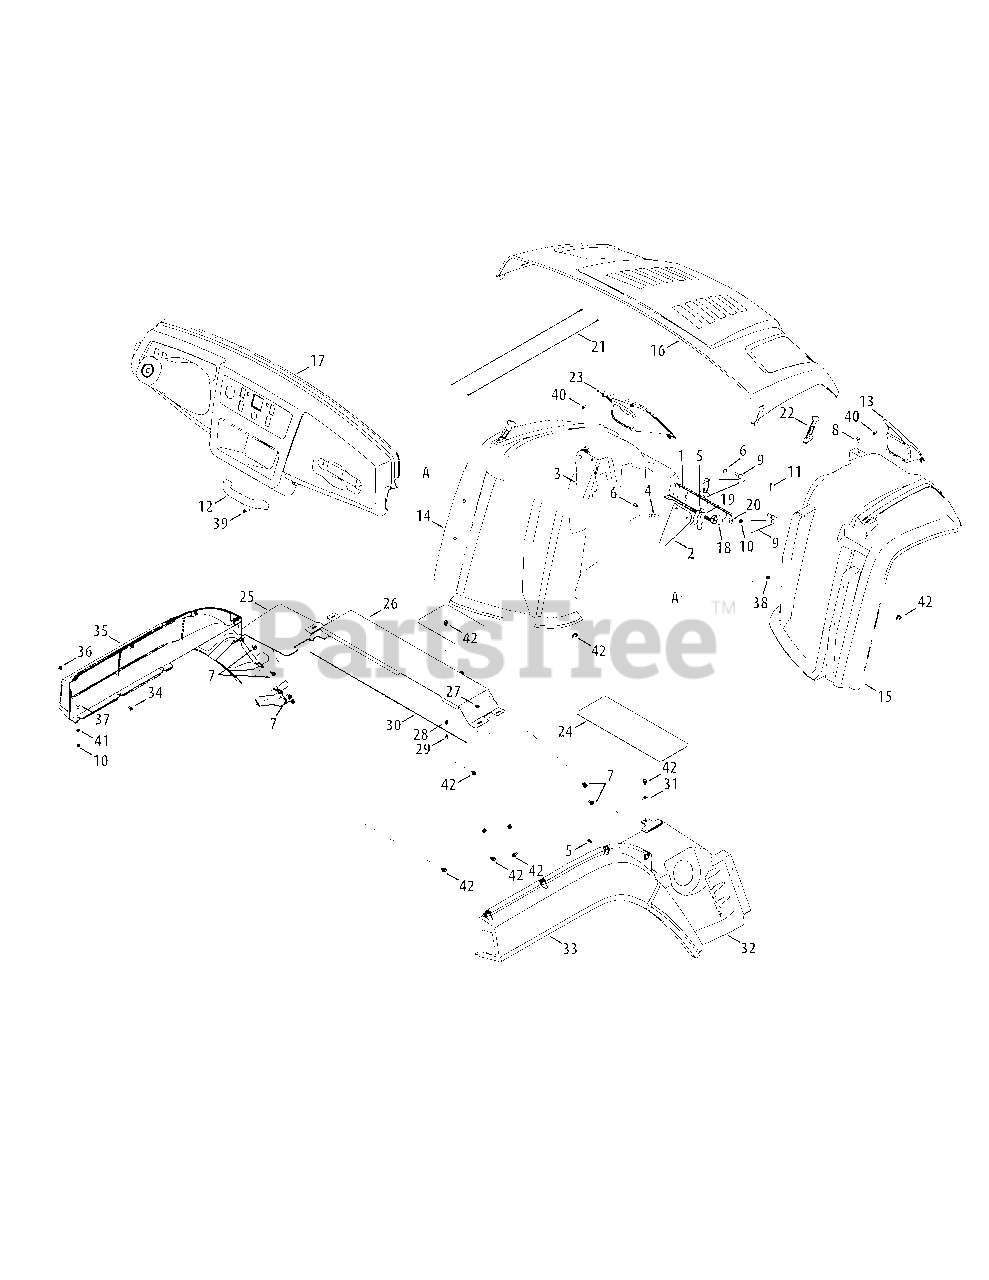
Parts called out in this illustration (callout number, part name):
1	Channel, Frame, Cross
2	Bracket, Hood/dash, Mount, Rh
3	Bracket, Hood/dash, Mount, Lh
4	Screw, 1/4-20, 1.75, Gr5, Std
5	Screw, #12-16 x .50
6	Screw, TT, 1/4-20 x .500
7	Screw, TT, 1/4-15 x .500
8	Hex Head Screw, 1/4-20 x 1.00
9	Rod Assembly, Hood Mount
10	Nut, Flange Lock, 1/4-20
11	Cotter Pin, Internal .08 x 1.42
12	Handle, W/Screw 400/500 S
13	Head Light RH
14	Fender, Lh 4x4
15	Fender, Rh 4x4
16	Hood, 4x4, Green
17	Dash, Uv 4x4
18	Roller, Latch, Hood
19	Spring, Latch, Hood
20	Washer, Flat, .283 x .75 x .030
21	Cable, Hood
22	Strap, Hood
23	Head Light LH
24	Pad, abrasive, toe plate (4x4)
25	Fender, Lwr Lh Rr
27	Latch, Panel, 1/4 Turn
28	Spring, Comprs, .40 OD x .040
29	Spring, Clip
30	Insulator, Cover, UV
31	Washer, Bell, .340 x .872 x .060
32	Fender, Lower Rh Rr
33	Fender, Rh Rr
34	Shldr Screw, .280 x .310, 1/4-20
35	Fender, Lh Rr
36	Nut, Acorn, 1/4-20
37	Screw, Crg, 1/4-20, .62, Gr2
38	Nut, Hex Lock., 1/4-20
39	Screw, Machine, 1/4-20 x 1.00
40	Screw, Tt, 1/4-20 x .625, Hxind.
41	Washer, Flat 1/4"
42	Screw, tt, 5/16-18 x 0.750
